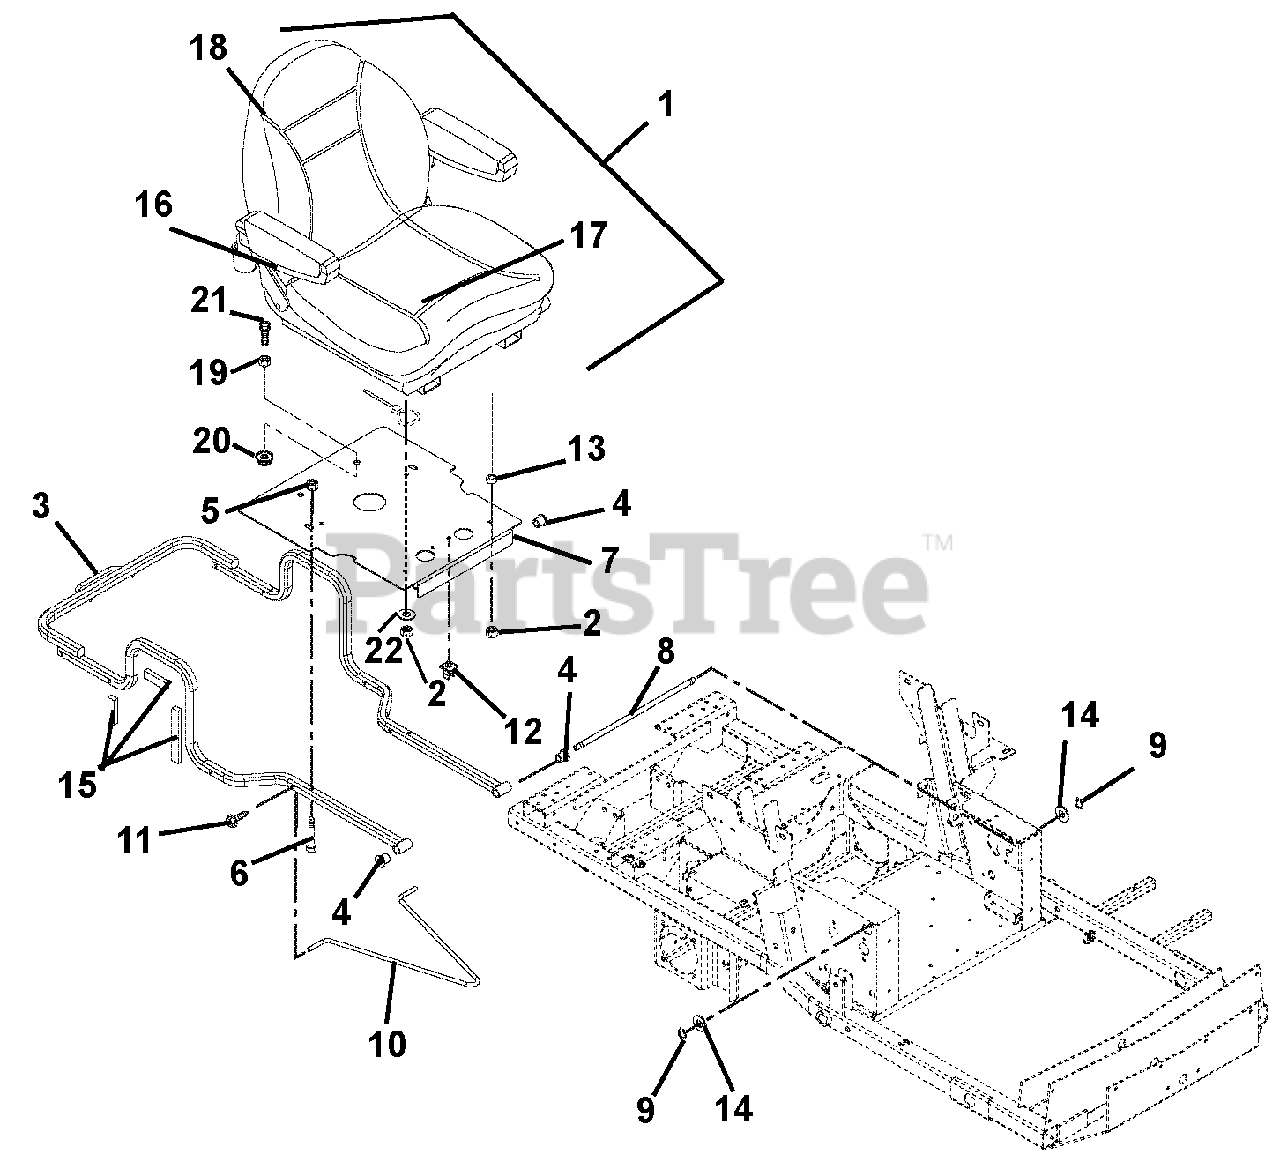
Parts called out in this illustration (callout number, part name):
1	SEAT,
2	@NUT-LK-TOP-FLG .31-18 YWZC
3	WMT, HOOD FRAME
4	BSHG-FLG .515X.750X.745X1.00NY
5	@NUT-LK-TOP-FLG .38-16 YWZC
6	BLT, .38-16X1.50 RIB NECK YWZC
7	WMT, SEAT PIVOT MOUNT
8	ROD - SEAT FRAME PIVOT
9	RG-RTNG-EXT .500X.050 (SNAP)
10	ROD, SEAT PROP
11	@SCR-TAP .25-20X.50 HWH TR YWZ
12	CLIP-.38
13	BSHG-SLV .377X.624X.235
14	@WSHR-FL-STL.531X1.06X.095YWZC
15	VHB TAPE 4941F
16	KIT,ARMREST PAD ONLY 1 PER KIT
17	KIT,SEAT CUSHION
18	KIT,BACK CUSHION
19	@NUT-HEX .50-13 YWZC
20	@NUT-LK-TOP-FLG .50-13 YWZC
21	@BLT-HEX .50-13X1.50 GR5 YWZC
22	WSHR-FL-STL .328X1.0X.094 YWZC
